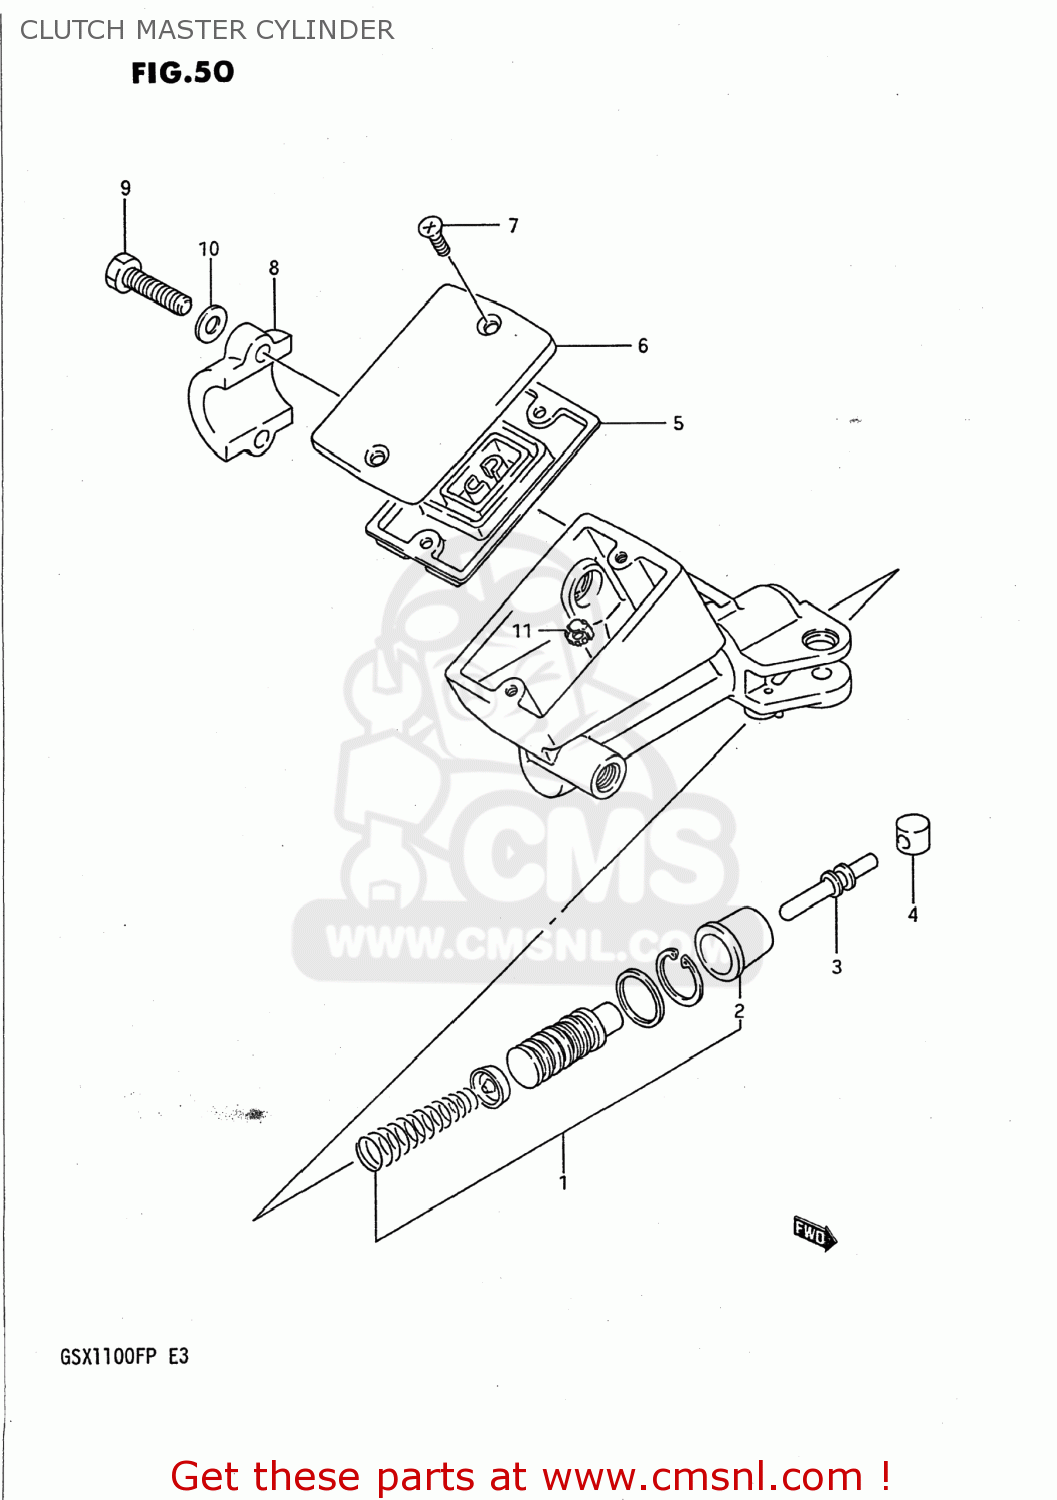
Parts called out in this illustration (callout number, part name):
1	PISTON & CUP SET
2	BOOT
3	ROD,PUSH
4	BUSH
5	6-1
6	CAP
7	SCREW
8	HOLDER
9	BOLT
10	WASHER
11	PROTECTOR
